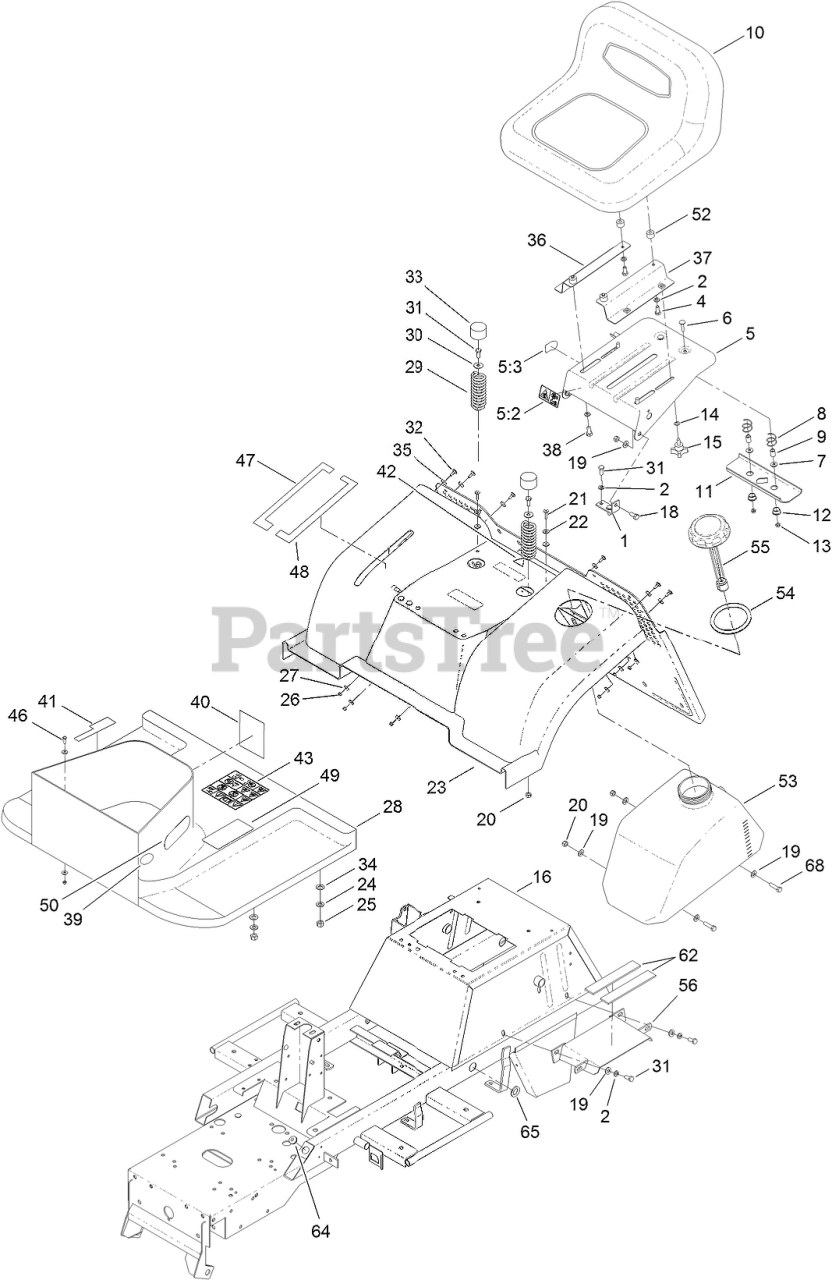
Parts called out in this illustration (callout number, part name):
1	BRACKET-SUPPORT, SEAT
2	WASHER-LOCK
4	SCREW-HH
5	SEAT PAN ASM
5:2	DECAL-DANGER
5:3	DECAL-SWITCH
6	BOLT-CARRIAGE
7	WASHER-FLAT
8	SPRING-SEAT
9	SPACER-SPLIT
10	SEAT ASM
11	BRACKET
12	BUSHING
13	NUT-LOCK
14	WASHER-SPRING
15	KNOB-ADJUSTMENT
16	FRAME-CHASSIS
18	SCREW-SUPPORT, SEAT
19	WASHER-PLAIN
20	NUT-LOCK, NI
21	SCREW-HSFH
22	WASHER-FINISH
23	FENDER-REAR
24	WASHER-FLAT
25	NUT-LOCK, NI
26	NUT-LOCK
27	WASHER-FLAT
28	FOOTREST ASM
29	SPRING-SEAT
30	WASHER-PLAIN
31	SCREW-HH
32	BOLT-CARRIAGE
33	CAP-HUB
34	WASHER-RUBBER
35	WASHER-RUBBER
36	BRACKET-SEAT, RH
37	BRACKET-SEAT, LH
38	SCREW-HHF
39	DECAL-BRAKE, PARKING
40	DECAL-STARTING
41	DECAL-OPERATION, HYDRO
42	DECAL-BAG TO FRAME
43	DECAL-DANGER
46	SCREW-HH
47	DECAL-HOC, LH
48	DECAL-HOC, RH
49	DECAL-OPERATION
50	DECAL-TOWER
52	SHIM-SEAT
53	TANK-FUEL
54	PROTECTOR-NECK, FILLER
55	CAP-FUEL
56	BRACKET-TANK, FUEL
62	STRIP-RUBBER, FUEL TANK
64	GROMMET
65	GROMMET
68	SCREW-HH
